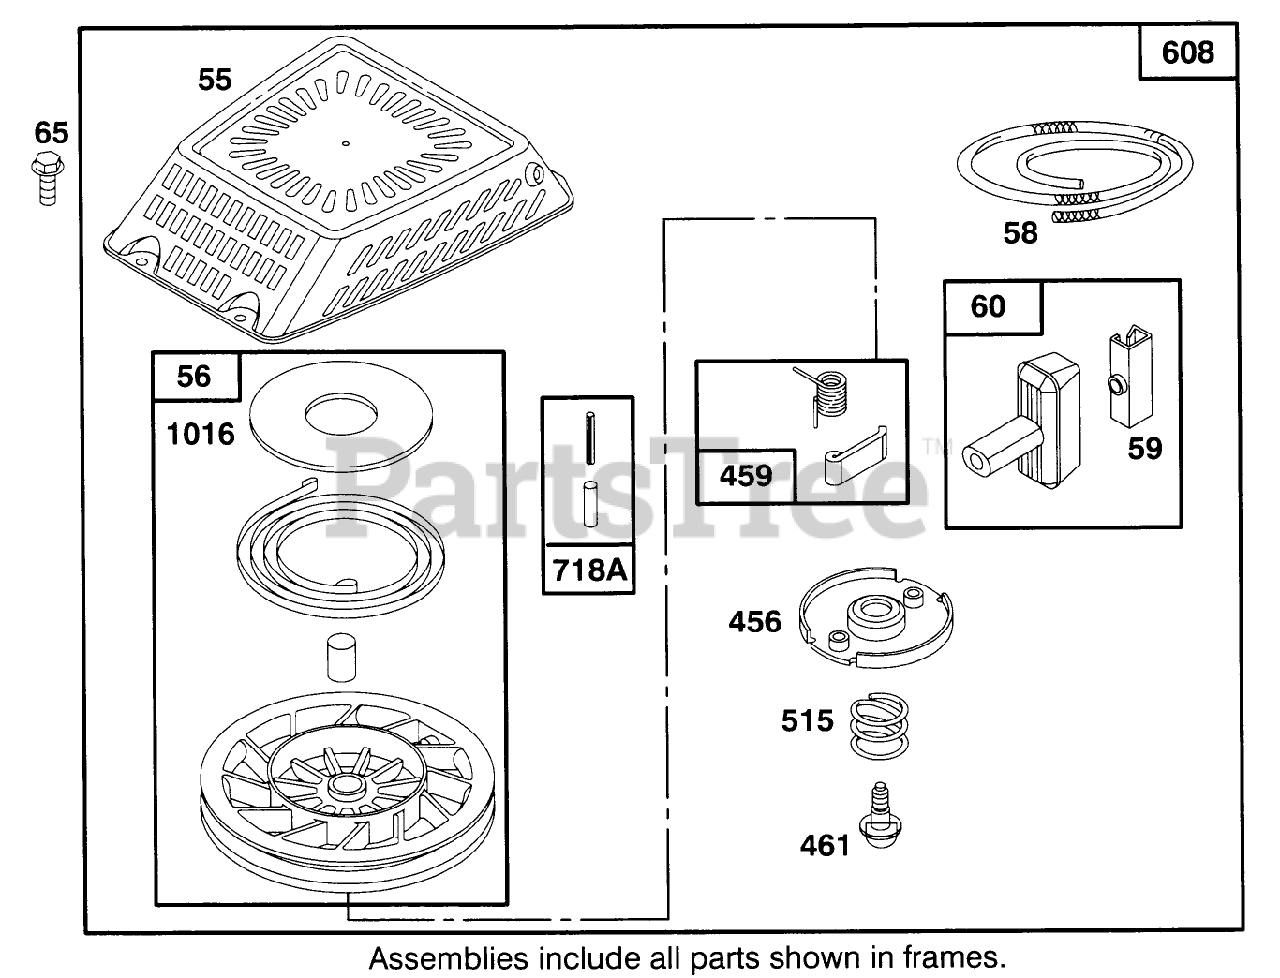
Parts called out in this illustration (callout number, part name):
59	INSERT-HANDLE, REWIND
456	RETAINER - SPRING
515	SPRING - RETAINER
